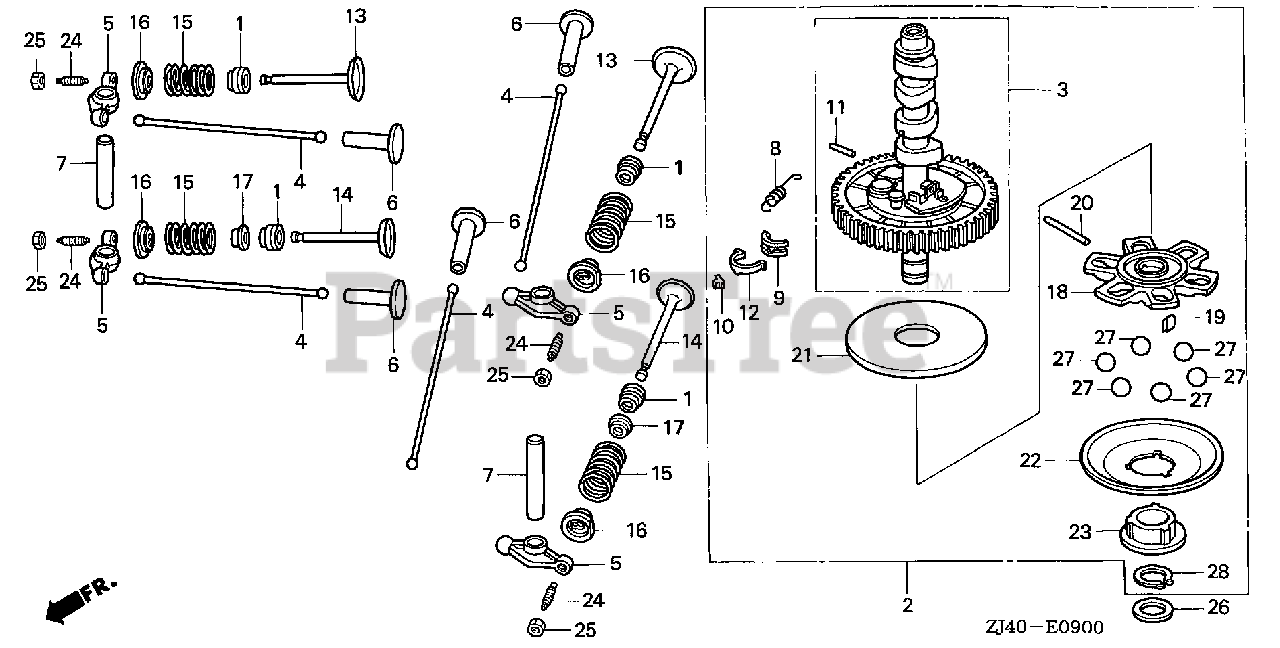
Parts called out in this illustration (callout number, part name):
1	SEAL, VALVE STEM
2	CAMSHAFT ASSY.
3	CAMSHAFT
5	ARM, VALVE ROCKER
6	LIFTER, VALVE
7	SHAFT, ROCKER ARM
8	SPRING, WEIGHT RETURN
9	HOLDER, DECOMPRESSION PIN
10	PIN A, DECOMPRESSION (7.85)
10	PIN B, DECOMPRESSION (7.95)
10	PIN C, DECOMPRESSION (8.05)
10	PIN D, DECOMPRESSION (8.15)
10	PIN E, DECOMPRESSION (8.25)
11	ROD, DECOMPRESSION
12	SPRING, DECOMPRESSION PIN HOLDER
13	VALVE, IN.
14	VALVE, EX.
15	SPRING, VALVE
16	RETAINER, IN. VALVE SPRING
17	SEAT, VALVE SPRING
18	HOLDER, GOVERNOR WEIGHT
19	PLATE, GOVERNOR WEIGHT HOLDER
20	PIN, GOVERNOR WEIGHT HOLDER
21	PLATE, GOVERNOR (LOWER)
22	PLATE, GOVERNOR SLIDER
23	SLIDER, GOVERNOR
24	SCREW, TAPPET ADJUSTING
25	NUT, TAPPET ADJUSTING
26	WASHER, THRUST (17.2MM)
27	BALL, STEEL (18)
28	CIRCLIP, OUTER (17MM)
